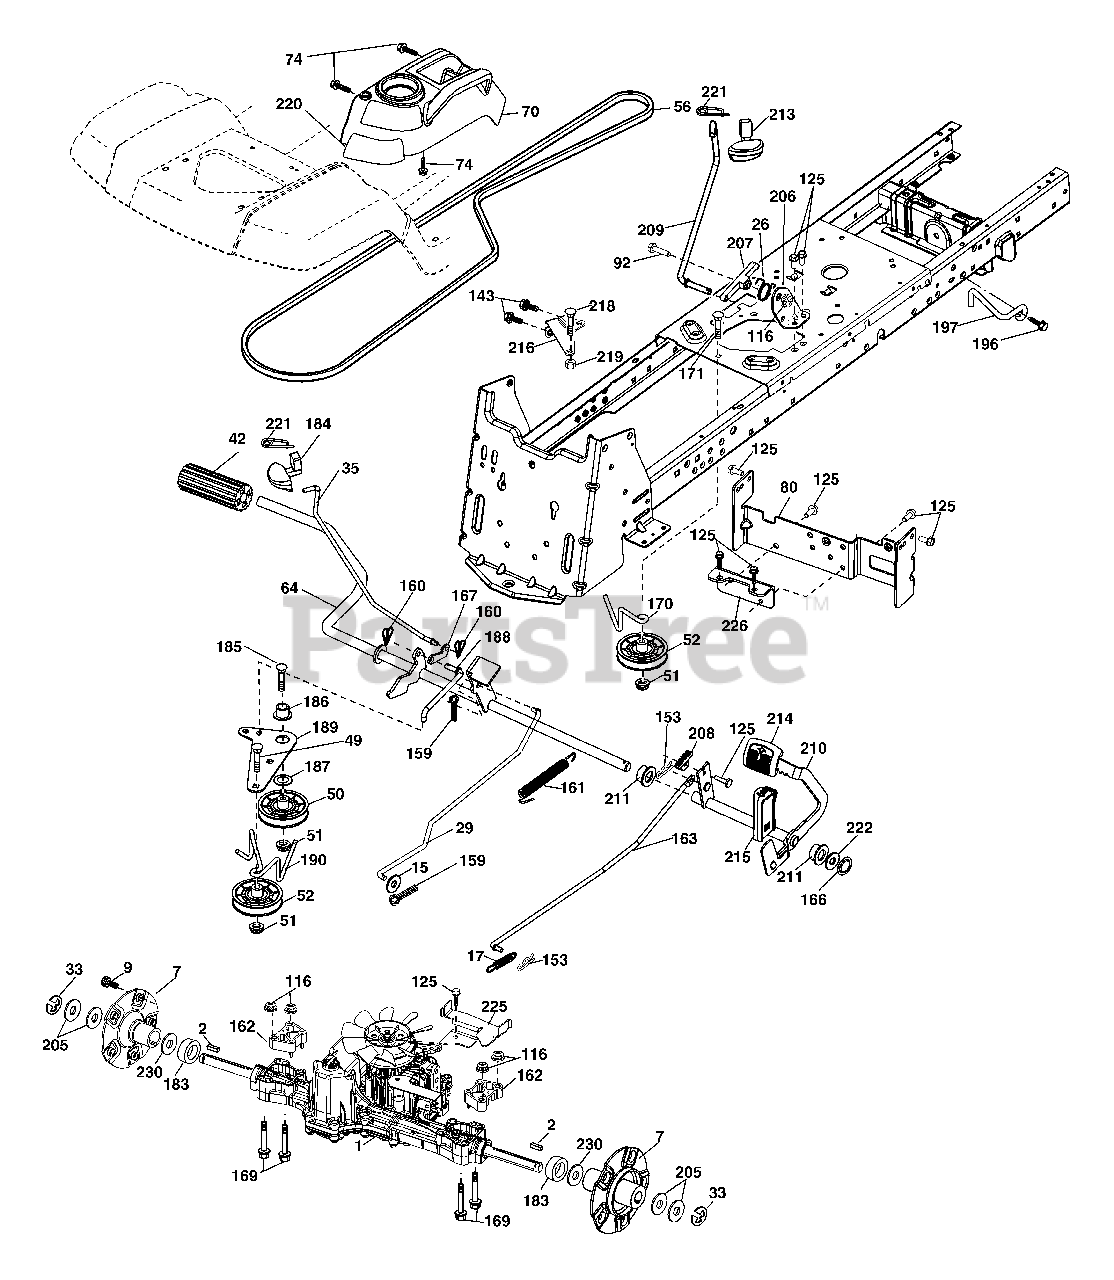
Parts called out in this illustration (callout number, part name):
2	Key 1/4 x 2.5
7	Hub Asm. Wheel
9	Bolt Hub Wheel
15	Washer 13/32 x 13/16 x 16 Ga.
17	Spring, Brake
26	Spring Return Cruise
29	Rod, Brake
35	Rod, Brake, Park
42	Cover, Foot Pedal
50	Pulley Idler Flat
51	Lock Nut 3/8-16
52	Idler V-Groove 910" Offset
56	V-Belt, Drive
64	Shaft Asm. Pedal Brake Control
70	Control Asm.
74	Screw 1/4 x 1/2
80	Bracket Strap Torque
96	Bolt Fin Hex 5/16-18 unc x 1.25
116	Nut Lock Hex Flange 5/16-18
125	Screw 5/16-18 x 3/4
143	Screw Thdrol 5/16-18 x 1/2
153	Retainer Spring
159	Pin Cotter 1/8 x 3/4
160	Retainer Clip
161	Spring, Return, Clutch
162	Spacer Transaxle
163	Rod Pedal Control
166	Nut Push .625
167	Latch Brake Parking
169	Bolt Hex Flghd 5/16-18 x 3.75
170	Keeper Belt Centerspan
171	Bolt RDHD SQNK 3/8-16UNC x 2
183	Spacer Split
184	Handle Parking Brake
185	Bolt Rdhd Sqnk 3/8-16 x 2-1/2
186	Spacer Retainer
187	Washer
188	Link Clutch Ground Drive
189	Bellcrank Ground Drive
190	Keeper Bellcrank Ground Drive
196	Screw 3/8-16 x 1
197	Bracket Clutch Anti-Rotation
206	Bracket Mount Latch Cruise
207	Latch Control Cruise
208	Gear Sector Control Cruise
209	Rod Control Cruise
210	Rocker Asm. Pedal Control
211	Bearing Nylon
213	Knob Control Cruise
214	Pedal Forward
215	Pedal Reverse
216	Bracket Pulley Idler
218	Bolt Fin Hex 5/16-18 unc x 1-1/4
219	Spacer Fender
220	Reflector RH
221	Retainer Spring Clip Handle
222	Washer 21/32 x 1-1/4 x 10 Ga.
225	Keeper Belt Trans.
226	Bracket Mount Touque
230	Washer Harden
